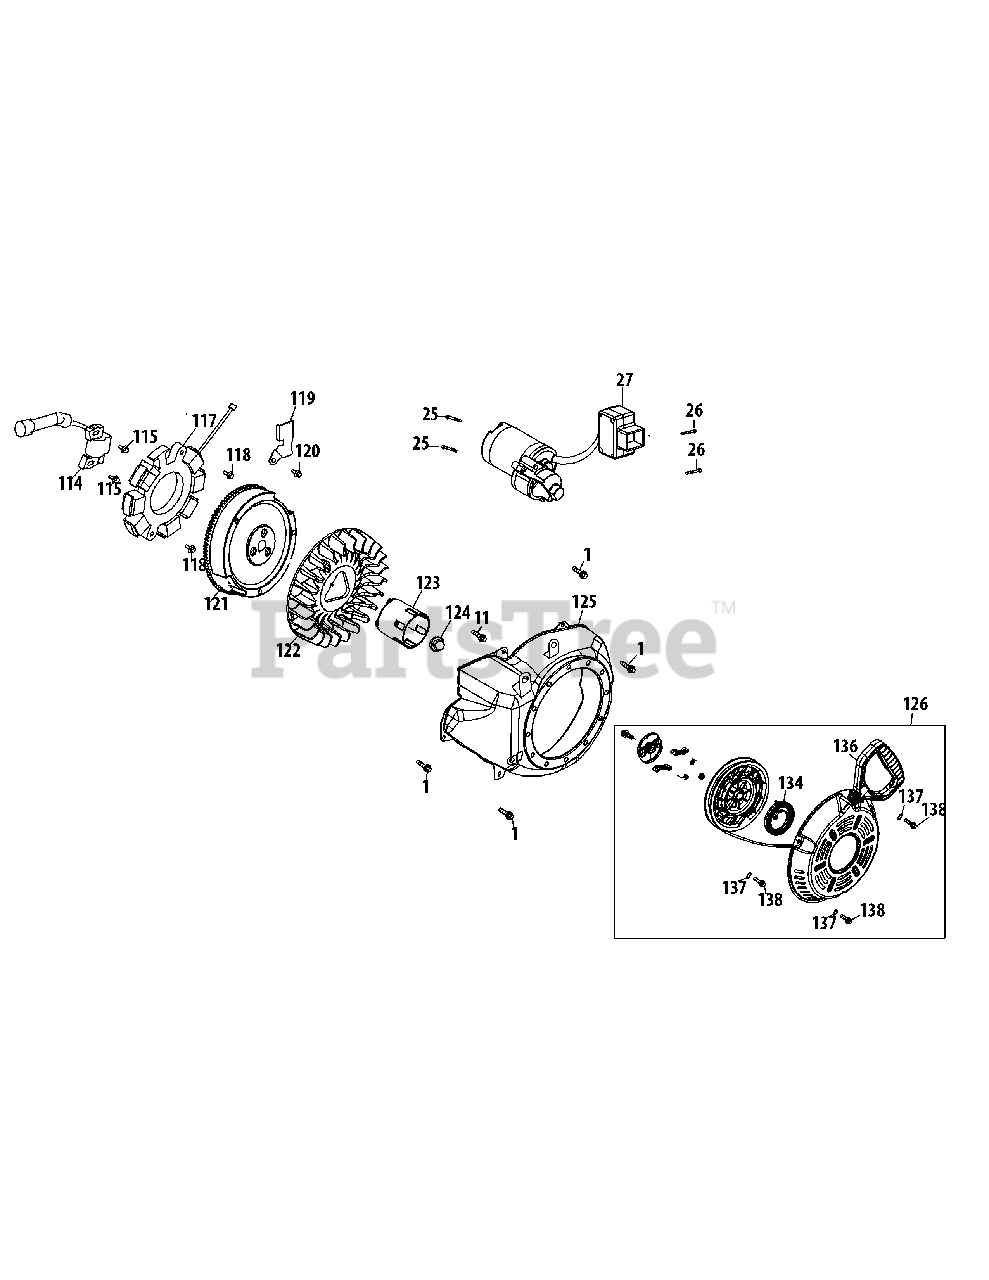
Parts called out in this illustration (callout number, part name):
1	BOLT M6×12
11	BOLT M6×16
25	BOLT M8×55
26	BOLT M4×55
27	ELECTRIC STARTER
114	IGNITION COIL ASSEMBLY
115	IGNITION COIL BOLT
117	ALTERNATOR ASSEMBLY
118	BOLT M6×30
119	WIRE PLATE
120	BOLT M6×8
122	COOLING FAN
123	STARTER CUP
124	NUT M16×1.5
125	BLOWER HOUSING
126	RECOIL STARTER
134	RECOIL SPRING
135	BLOWER HOUSING
136	STARTER HANDLE
137	GASKET 6
138	BOLT M6×10
